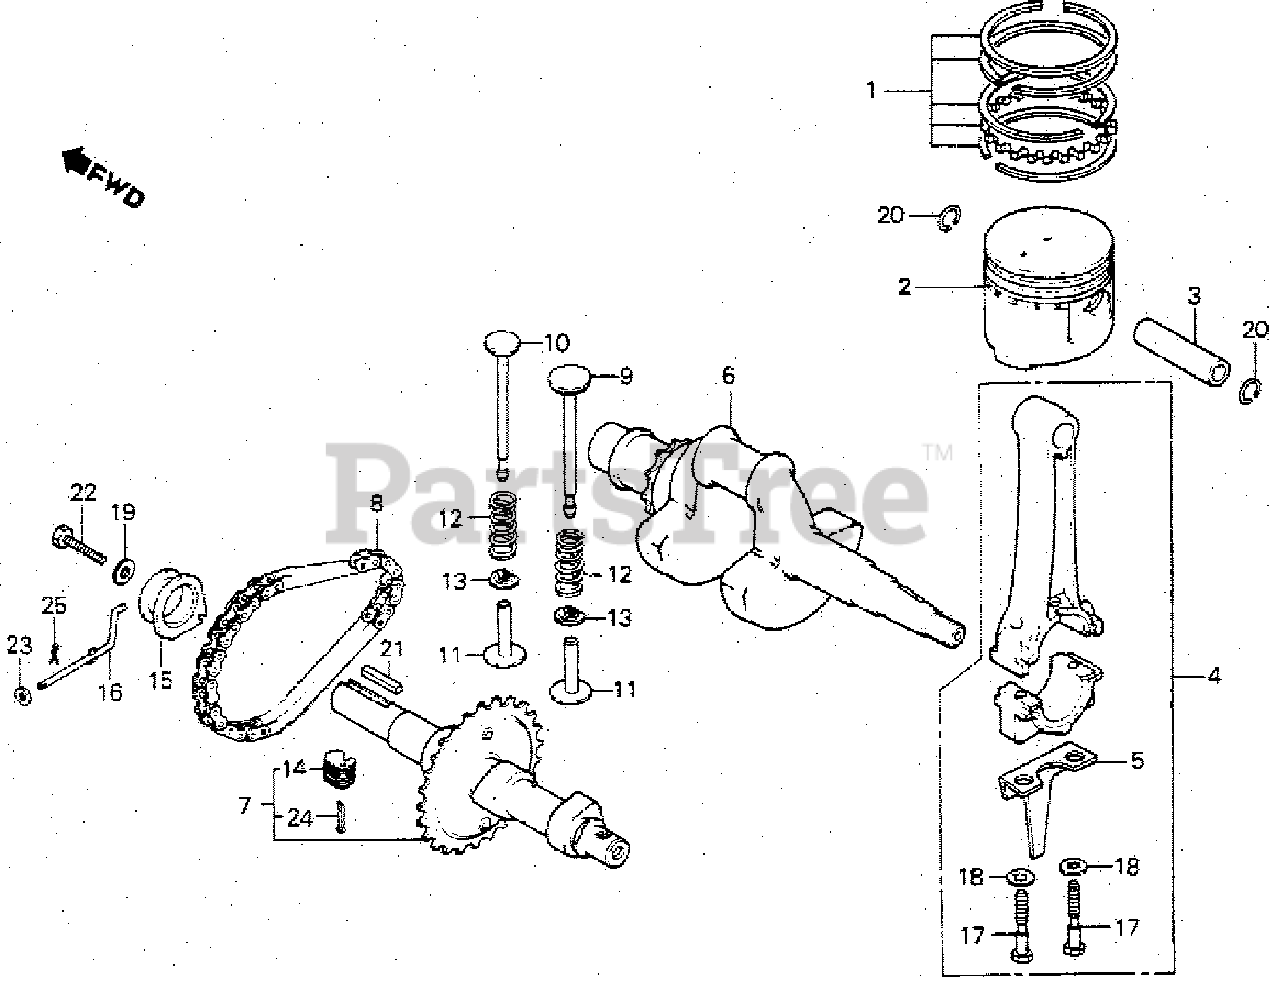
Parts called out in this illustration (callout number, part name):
1	RING SET, PISTON (STD)
1	RING SET, PISTON (OS 0.25)
1	RING SET, PISTON (OS 0.50)
1	RING SET, PISTON (0.75)
2	PISTON (STD)
2	PISTON (OS 0.25)
2	PISTON (OS 0.50)
2	PISTON (0.75)
3	PIN, PISTON
4	ROD ASSY., CONNECTING
5	DIPPER, CONNECTING ROD
6	CRANKSHAFT (L-TYPE)
7	CAMSHAFT ASSY.
8	CHAIN, CAM
9	VALVE, IN.
10	VALVE, EX.
11	LIFTER, VALVE (39.6MM)
11	LIFTER, VALVE (39.9MM)
12	SPRING, VALVE
13	RETAINER, VALVE SPRING
14	WEIGHT, GOVERNOR
15	SLIDER, GOVERNOR
16	SHAFT, GOVERNOR ARM
17	BOLT, CONNECTING ROD (7MM)
18	WASHER, LOCK (7MM)
19	WASHER (8MM)
20	CLIP, PISTON PIN (15MM)
21	KEY (5X5X33)
22	BOLT, HEX. (8X25)
23	WASHER, PLAIN (5MM)
24	PIN, COTTER (3.0X45)
25	PIN, LOCK (8MM)
